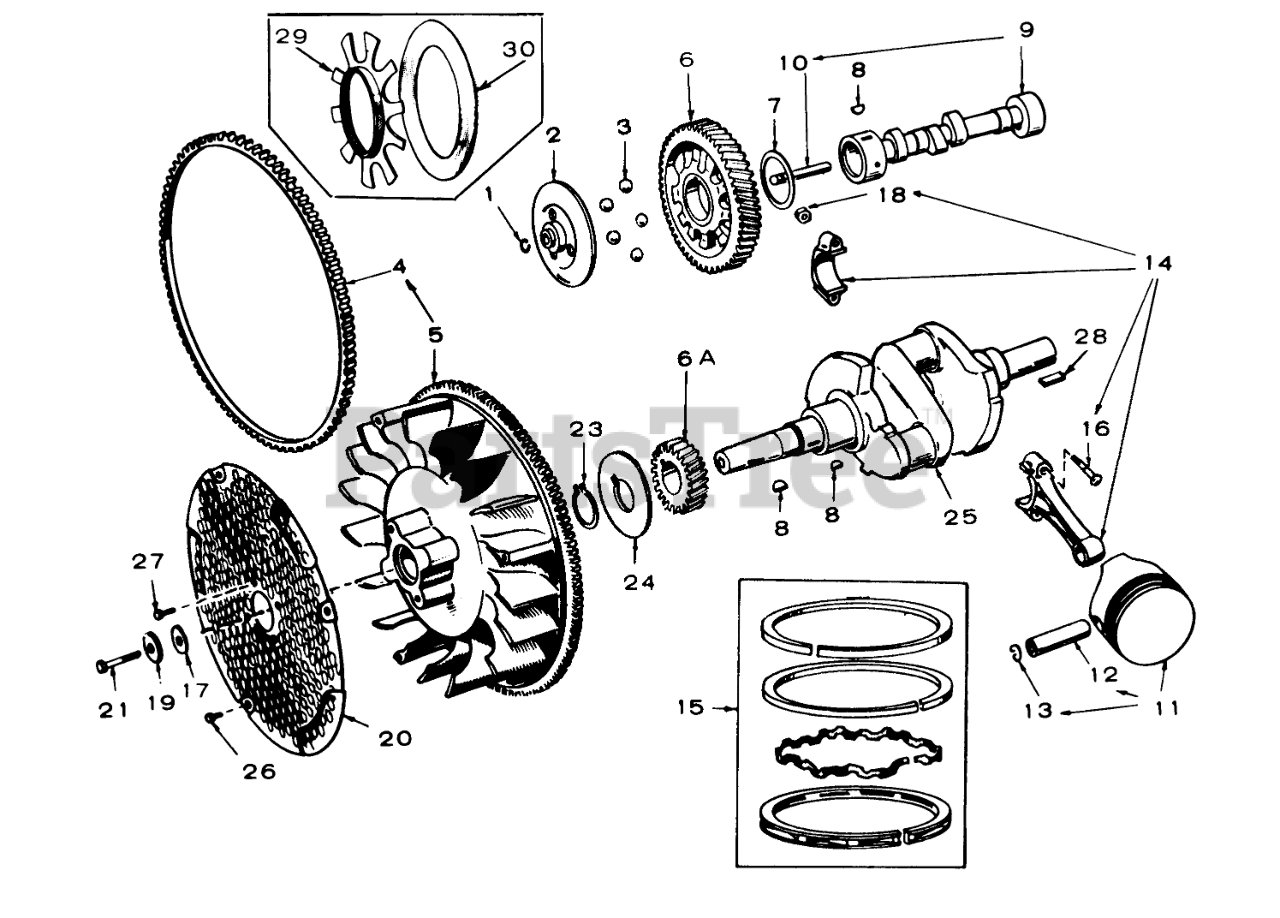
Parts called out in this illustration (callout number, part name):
8	Key
8	Key, Cam Crankshaft Gear
8	Key, Flywheel
9	Camshaft (Includes Center Pin)
11	PISTON AND PIN (INCLUDES RETAINING RINGS)
11	.005" Oversize
11	.030" Oversize
11	.040" Oversize
14	ROD ASSEMBLY, CONNECTING
14	.010" Undersize
14	.020" Undersize
14	.030" Undersize
15	RING SET, PISTON
15	.030" Oversize
15	.040" Oversize
17	Washer 7/16
18	Lock Nut-Connecting Rod
19	Lockwasher 7/16 Flywheel
21	Hex Bolt
28	Crankshaft Key-PTO Side
